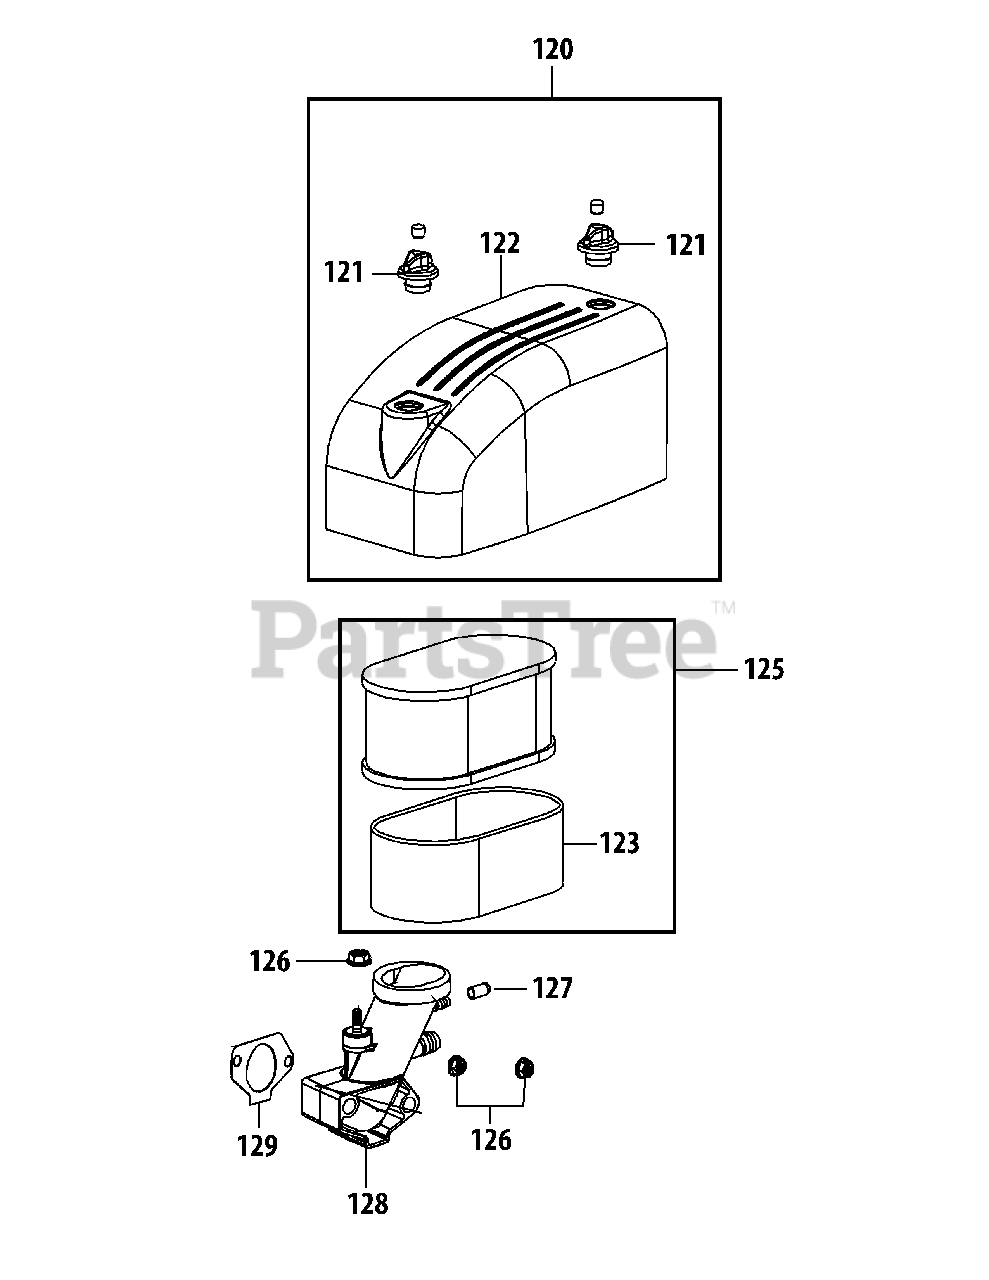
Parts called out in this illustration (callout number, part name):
120	Air Filter Cover Assembly
121	Air Filter Lock Nut
122	Air Filter Cover
123	Sponge Filter
125	Air Filter Assembly
125	Genuine Factory Parts AIR FILTER
127	Rubber Cap
128	Manifold/Add Air Hole
129	Manifold Gasket/Add Air Hole
